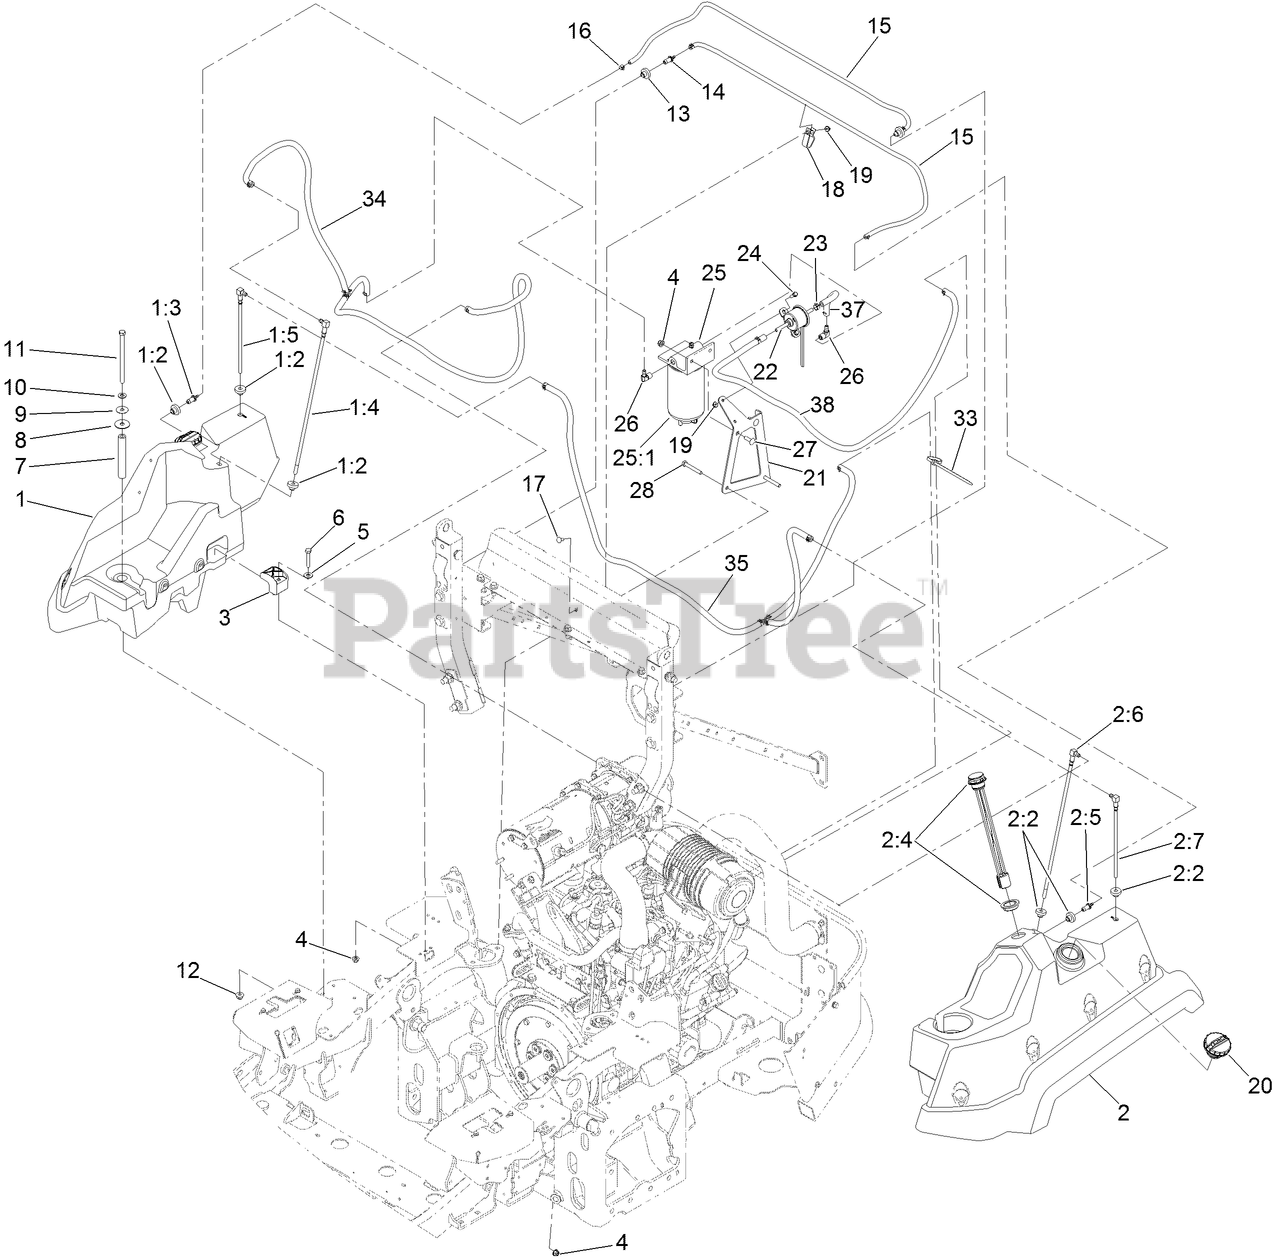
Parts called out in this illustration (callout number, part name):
1	RH FUEL TANK ASM
1:2	BUSHING
1:3	FITTING-ORIFICE, STRAIGHT
1:4	PICK-UP-FUEL
1:5	RETURN-FUEL
2	LH FUEL TANK ASM
2:2	BUSHING
2:4	GAUGE-FUEL
2:5	FITTING-ORIFICE, STRAIGHT
2:6	PICK-UP-FUEL
2:7	RETURN-FUEL
4	NUT-HF, NI
5	WASHER-FLAT
6	SCREW-HH
7	TUBE-SPACER
8	WASHER-RUBBER
9	WASHER-PLAIN
10	WASHER-FLAT
11	SCREW-HH
12	NUT-HF, NI
13	BUSHING
14	FITTING-ORIFICE, STRAIGHT
15	HOSE-VENT, TANK
16	CLAMP-HOSE
17	SCREW-CARR
18	CLAMP-HOSE
19	NUT-HF
20	CAP-FUEL, DIESEL
21	BRACKET-FILTER, FUEL
22	PUMP-FUEL, ELECTRIC
23	CLAMP-HOSE
24	SCREW-HWH
25	SEPARATOR FILTER ASM
25	FILTER-WATER/FUEL SEPERATOR
25:1	FILTER-FUEL/WATER SEPARATOR
26	FITTING-HYD, 90
27	SCREW-CARR
28	SCREW-HH
33	TIE-PLASTIC
34	FUEL SUCTION LINE ASM
35	FUEL RETURN LINE ASM
37	HOSE-FUEL
38	HOSE-FUEL
